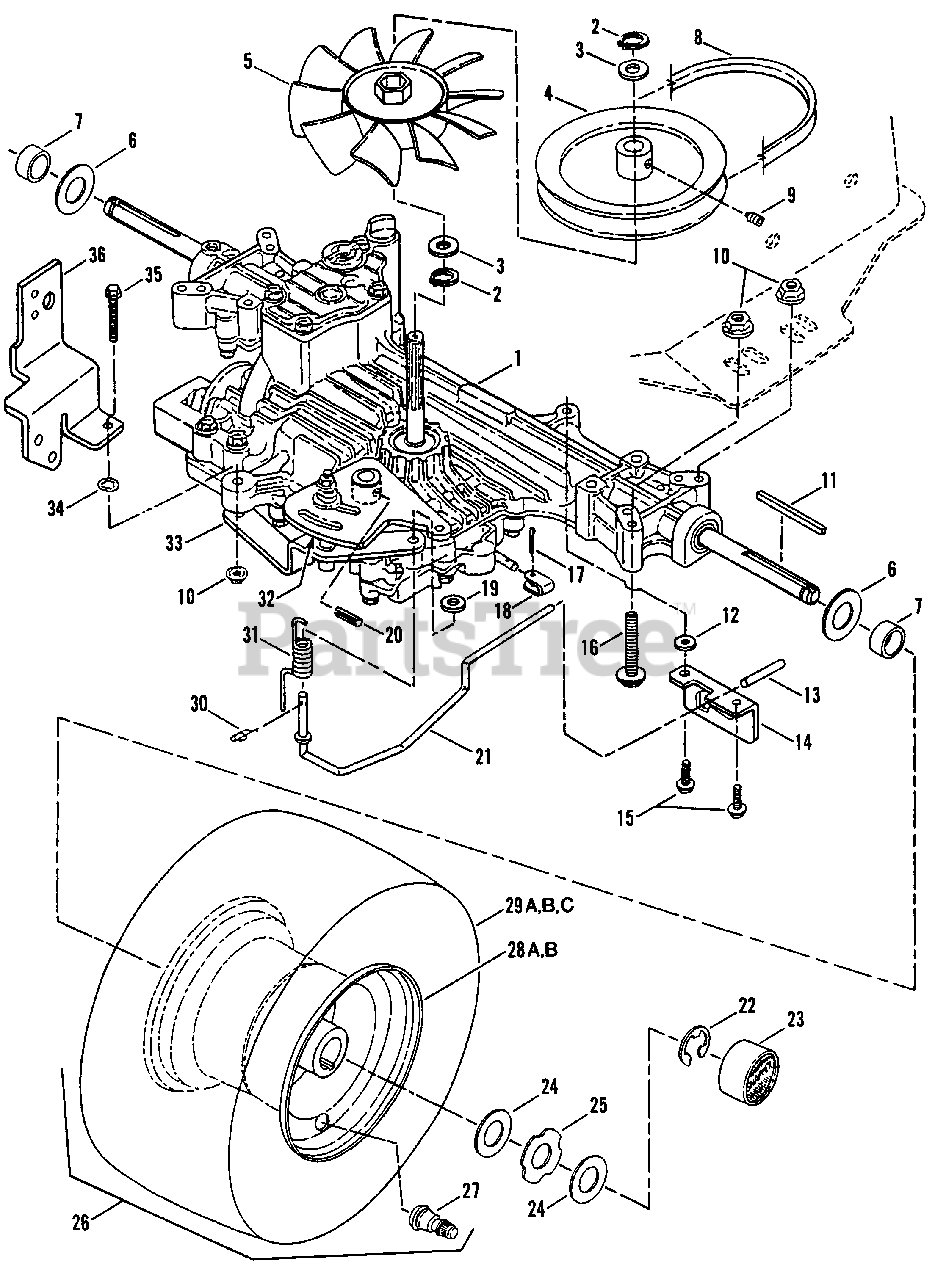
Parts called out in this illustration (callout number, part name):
1	TRANSAXLE, Hydro Drive, Tuff-Torq Model K50
2	RING, Retaining
3	WASHER, Fan/Hub
4	PULLEY, Drive
5	FAN
6	WASHER, Flat, .132 x .781 I.D. x 1.5 O.D.
8	BELT, Traction Drive
9	SETSCREW, 1/4-20 x 5/16" Locking
10	NUT, 5/16-18 Hex Flange Lock
11	KEY, Square, 3/16 x 3/16 x 2 1/2"
12	WASHER, Flat, 3/4" O.D.
13	GRIP, Roll Release
14	DETENT, Roll Release
15	SCREW, 3/8-16 x 1 3/4" Self-Tapping
16	BOLT, 5/16-18 x 2 1/4" Hex Flange Lock
17	COTTER-PIN, 5/32 x 1"
18	LINK, Roll Release
19	WASHER
20	ROLL-PIN, Speed Control Arm
21	WIREFORM, Roll Release
22	RING, Retaining
23	HUB-CAP
24	WASHER, Flat, .07 x .77 I.D. x 1.31 O.D.
25	WASHER, Hub-Cap Retaining
26	ASSEMBLY, Rear Tire & Rim
27	VALVE, Air (Snap-in)
28A	RIM, 8 x 5.375
28B	RIM, 8 x 7.00
29A	TIRE, 18 x 7.50
29B	TIRE, 18 x 8.50
29C	TIRE, 18 x 9.50
30	COTTER-PIN, 5/16 Self-locking
31	SPRING, Torsion (Roll Release)
32	ASSEMBLY, Speed Control/Friction
33	SUPPORT, Friction Stud Assembly
34	RETAINER, 5/16 Bolt
35	BOLT, 5/16-18 x 2" Hex Flange Lock
36	BRACKET, Spool
